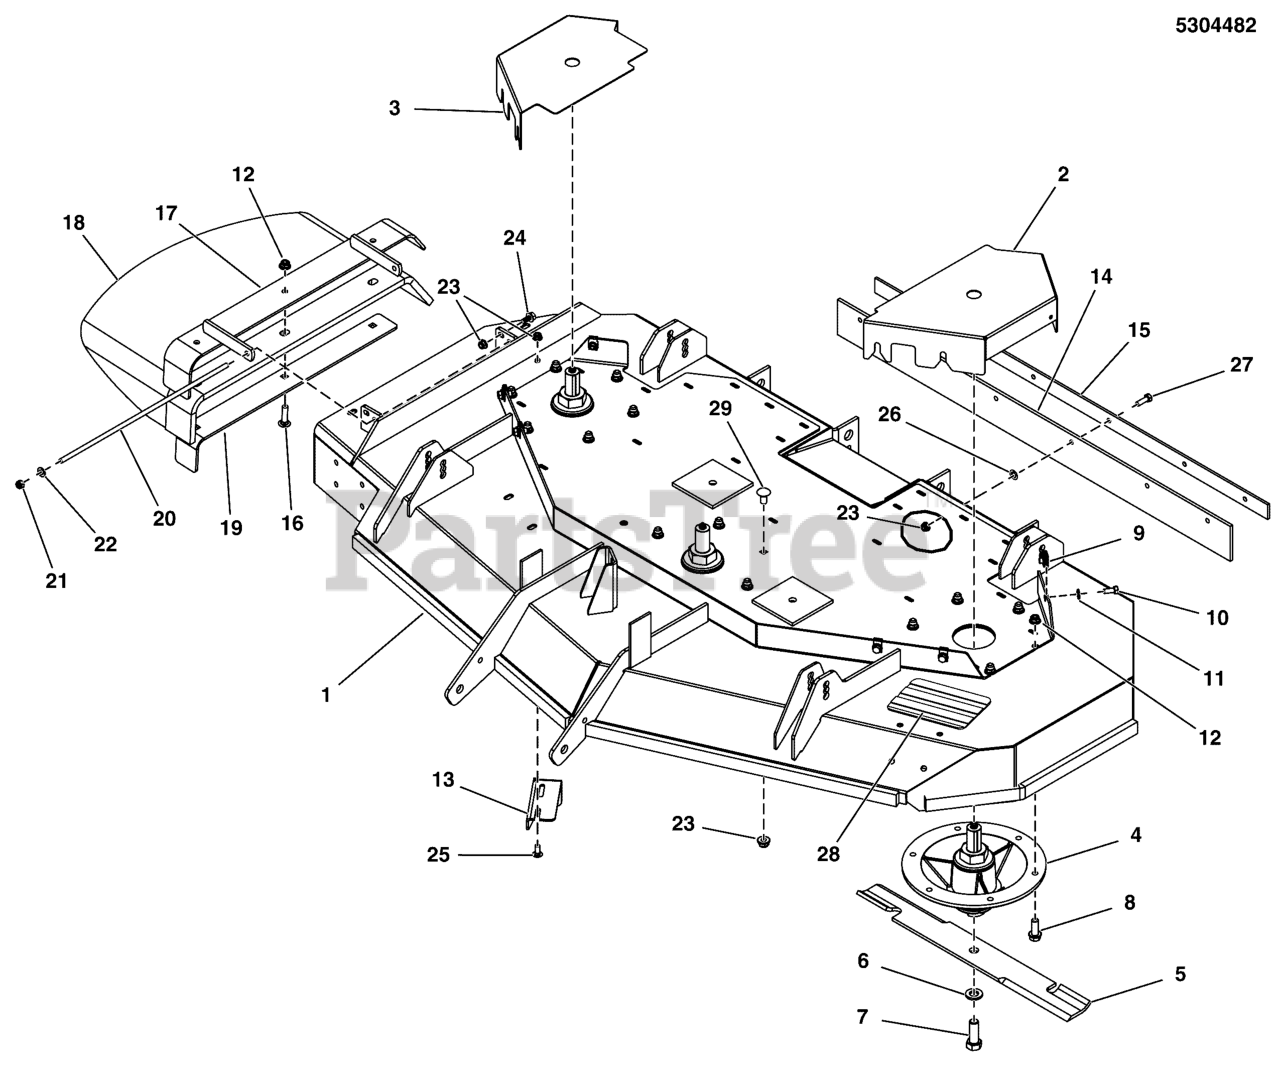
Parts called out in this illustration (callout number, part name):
1	DECK SHELL W/DECALS,61,F320Z,5414678B
2	GUARD, MOWER DECK, F320Z, LH - RED
3	GUARD, MOWER DECK, F320Z-61, RH - RED
4	SPINDLE ASSEMBLY
5	BLADE SET, 61 DECK (3)
6	WASHER, BLADE BOLT, 9/16" F436, CZ
7	BOLT, 5/8-11 X 1-3/4 GD8
8	BOLT, 3/8-16 X 1-1/4, FLANGE, GD 5, CZ
9	BODY CLIP, 5/16-18-7GA MATERIAL
10	BOLT, 5/16-18 X 1 GD5 CZ
11	WASHER, 5/16 F436 FLAT
12	NUT, 3/8-16 HEX NYLOCK FLANGE
13	PLATE, DEFLECTOR - BLK
14	FLAP, STRIPER, 61 DECK, IS3100 S200X
15	PLATE, SUPPORT - BLK
16	BOLT, 3/8-16 X 1-1/2, CARRIAGE, GD5, CZ
18	CHUTE, RUBBER DISCHARGE (5104442)
19	SUPPORT, DISCHARGE CHUTE - BLK
20	ROD, MOUNT, CHUTE 61, CZ
21	NUT, 5/16-24 HEX NYLON LOCK
22	WASHER, 5/16" SAE
23	NUT, 5/16-18 HEX NYLOCK FLANGE
24	BOLT, 5/16-18 X 3/4 GD5
25	BOLT, 5/16-18 X 3/4, CARRIAGE
26	5/16 PUSH-ON NUT RETAINER, STL, CZ
27	BOLT, 5/16-18 X 1 GD5 CZ
28	SAFETY WALK, 9.75 X 6.00
29	BOLT,3/8-16X1 1/4,GR5,CARRIAGE,ZC/CL
